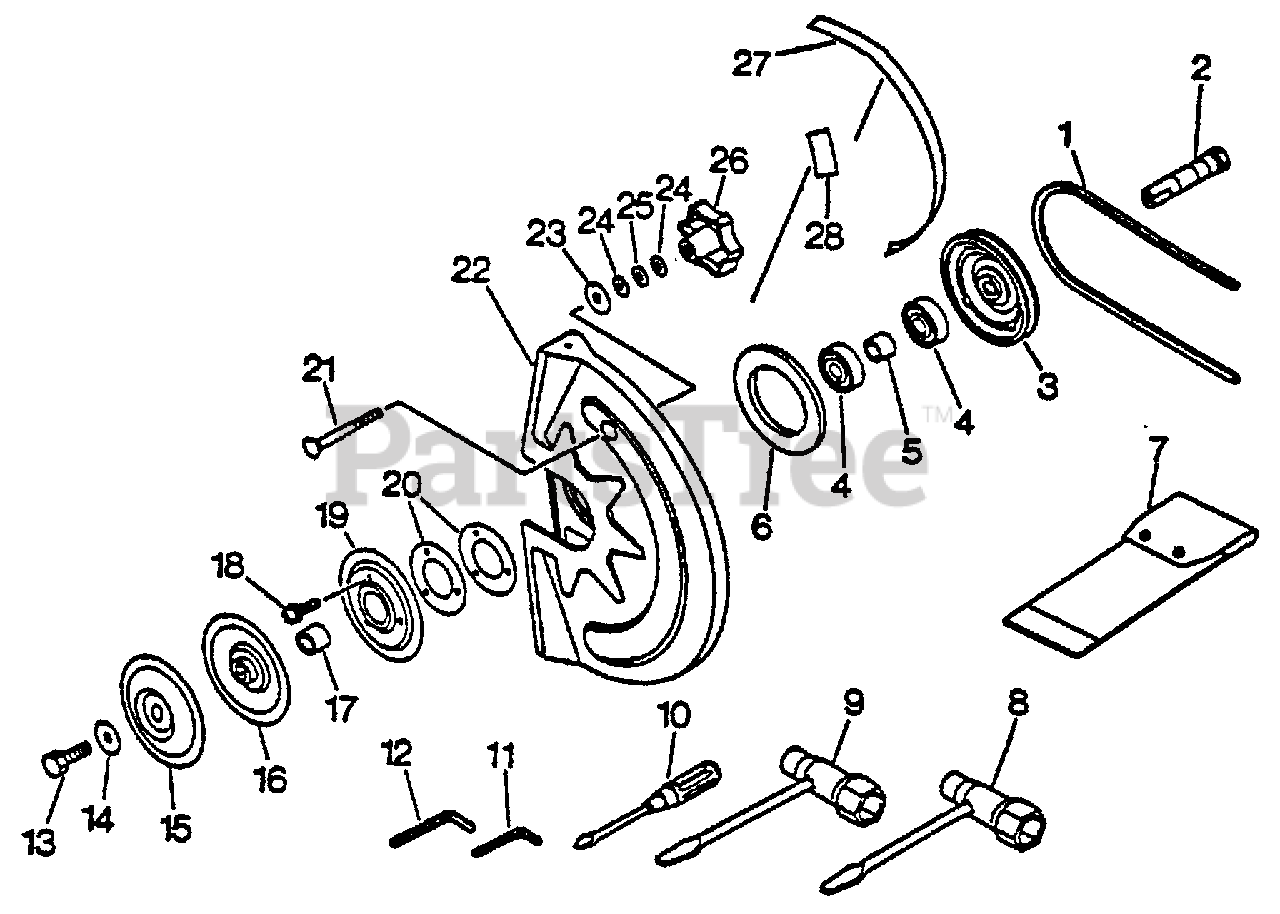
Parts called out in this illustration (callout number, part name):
4	BEARING, BALL - 6203
5	SPACER
7	BAG, TOOL
8	T-WRENCH - 13X19mm
9	T-WRENCH - 17X19mm
10	SCREWDRIVER
11	HEX KEY - 4mm
12	HEX KEY - 5mm
15	FLANGE, CUTTER
16	FLANGE, CUTTER
18	SCREW - 4X14
19	PLATE, CUTTER COVER
21	BOLT - 10X70
22	COVER, BLADE
24	WASHER - 10
25	LOCKWASHER - 10
27	LABEL - MARK
28	LABEL - ECHO
